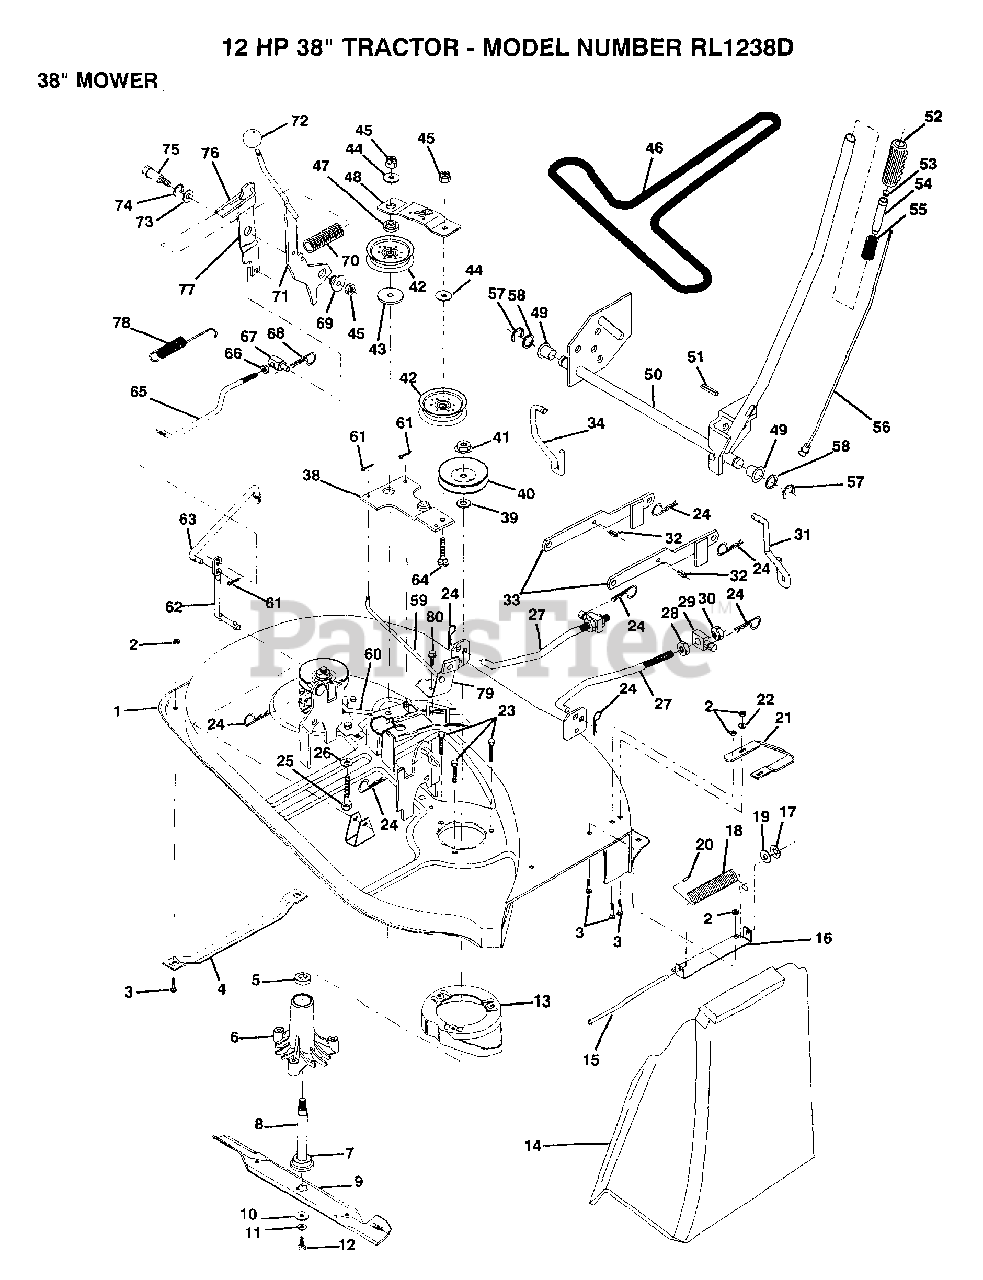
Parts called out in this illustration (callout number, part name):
3	BOLT
4	RUNNER-LH M
5	BEARING
6	HSG ASM MANDREL
7	BEARING.BALL
10	WASHER BLADE
12	BLADE BOLT
14	DEFLECTOR-SHLD T
15	ROD-HINGE T
17	NUT PUSH M
19	WASHER
20	CAP-SLEEVE LT
21	RUNNER RH
22	WASHER M
25	BOLT
26	WASHER GT
27	LINK.FRONT
28	NUT
29	TRUNION
30	NUT.LK.W/WSH.1/2.
31	LIFT LINK RH
32	"PIN,SPRING"
33	SUSP ARM ASM REAR
34	LINK LIFT LH
38	IDLER ARM ASSY
39	WASHER
42	FLAT IDLER PULLEY
43	SPACER RETAINER
44	WASHER GT
46	BELT-V.88.12.MW
47	RETAINER SPACER
48	IDLER ARM STIFF
49	NYLON BEARING
51	PIN-GROOVE LT
52	GRIP
58	WASHER
59	BRAKE ROD RH
60	BRAKE ROD LH
62	PIVOT ROD
63	CLUTCH ROD SECOND
64	BOLT
66	NUT
67	TRUNION
68	RETAINER M
69	BUSHING
71	CLUTCH ARM PRI AS
73	WASHER
74	RING
75	SHOULDER BOLT
76	SPRING KEEPER
77	CLUTCH ARM SECOND
78	RETURN SPRING
79	BRAKE ASM
80	SCREW
